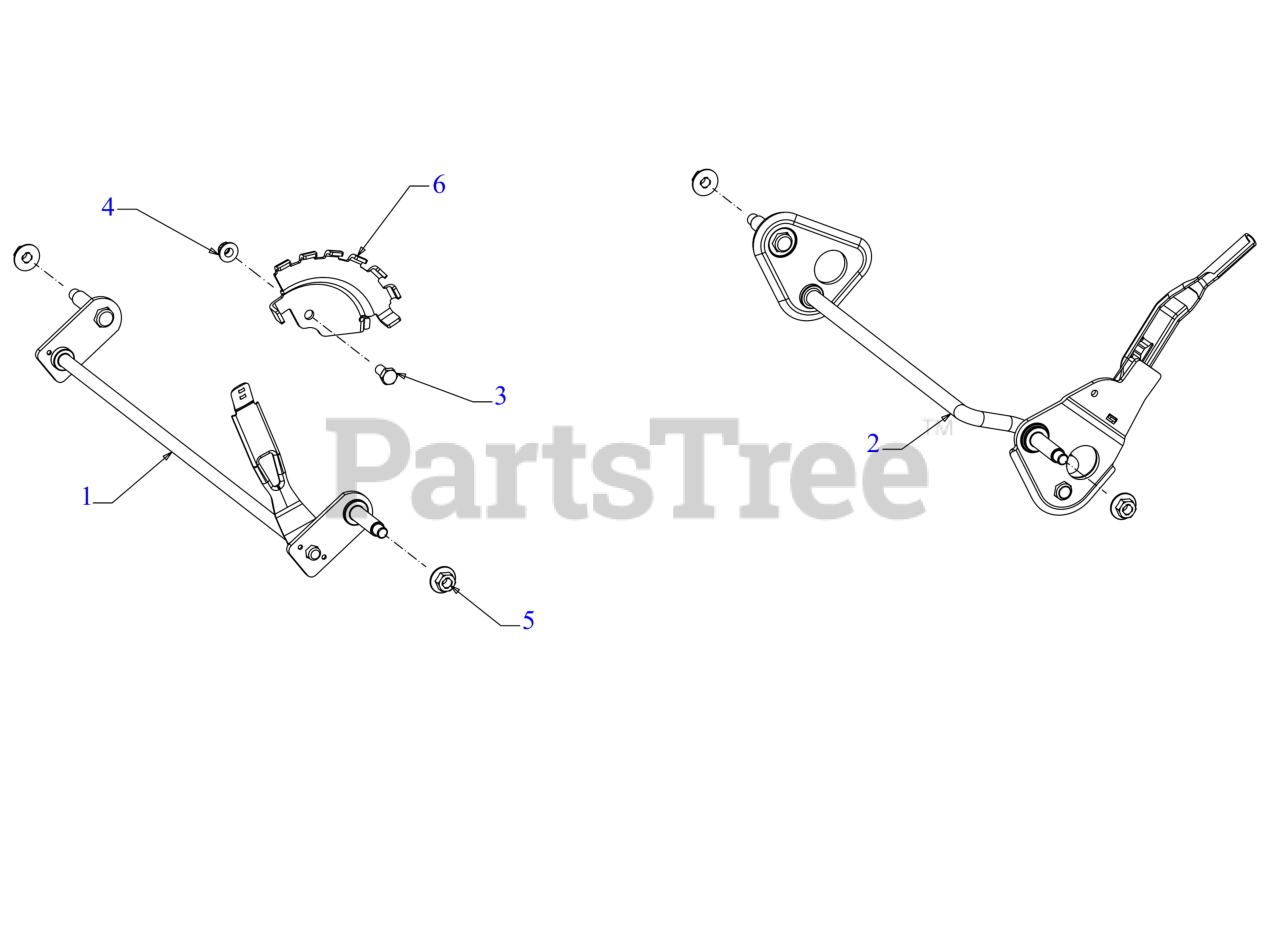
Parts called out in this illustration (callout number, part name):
1	FRONT DUAL AXLE (8" WHEEL)
2	AXLE (REAR) (w/HGT ADJUSTMENT)
3	SCREW 5/16-18X .625 GR5
4	FLANGE LOCK NUT 5/16-18
5	FLANGE LOCK NUT
6	23" HEIGHT ADJUSTMENT BRACKET(FRONT)
